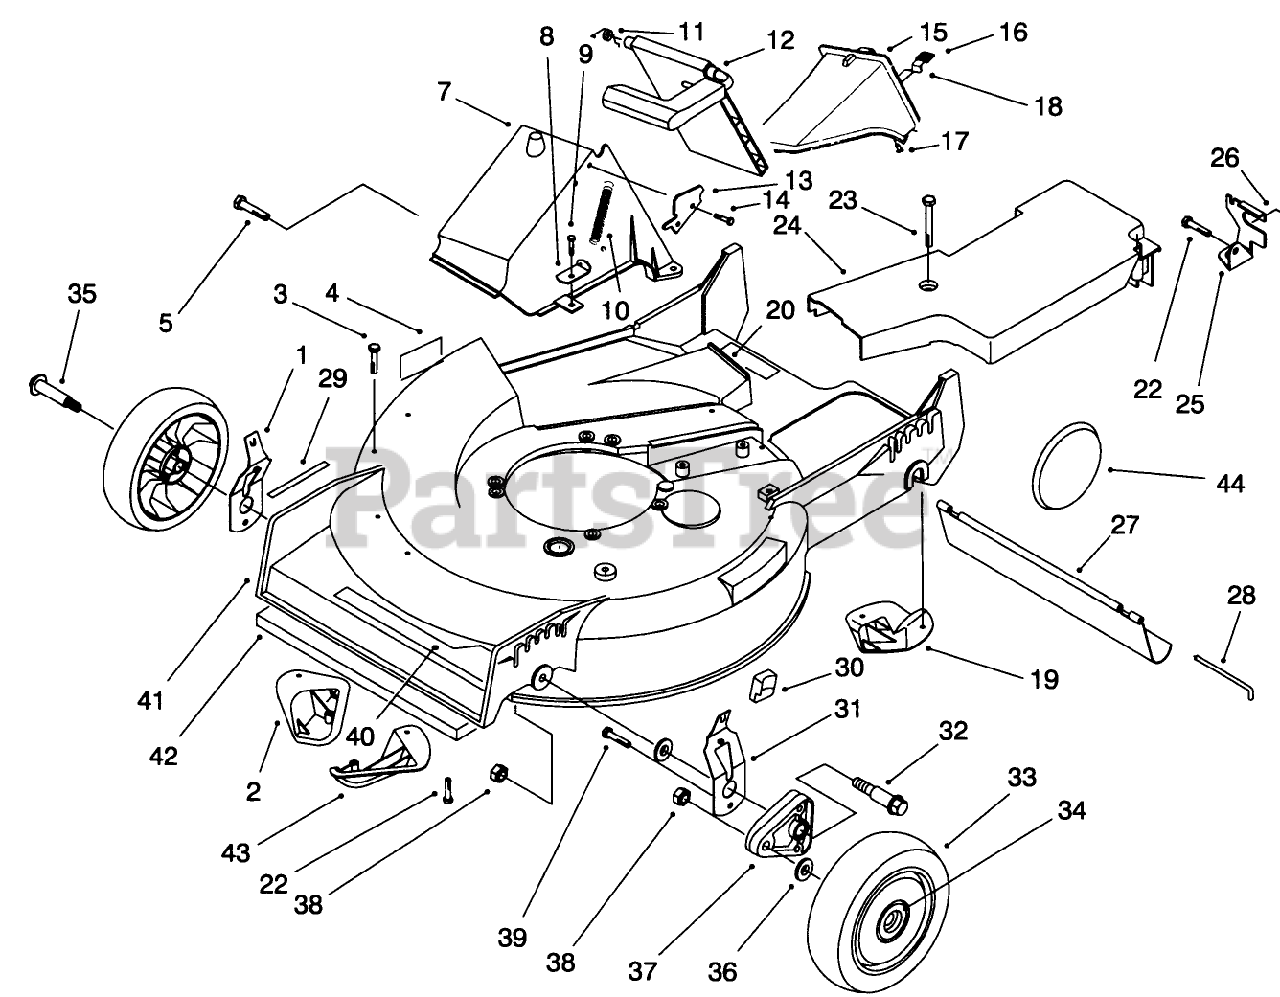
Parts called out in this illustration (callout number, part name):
1	RH SPRING ARM ASSEMBLY
2	KICKER-RH
3	SCREW-PPH
5	SCREW AND WASHER ASM
7	TUNNEL-DISCHARGE
8	BRACKET-SPRING
9	SCREW-HWH
10	SPRING-DOOR
11	RETAINER-DOOR
13	DOOR LATCH PLATE
14	SCREW-PLASTITE
15	DISCHARGE PLUG ASM
16	GRIP-LATCH
17	RIVET-HEAD, FLAT
18	LATCH-PLUG, DISCHARGE
19	KICKER-REAR
22	SCREW-HWHTF
23	SCREW-HWH
26	RETAINER-CABLE
28	ROD-SHIELD
30	KNOB-ARM
31	LH SPRING ARM ASSEMBLY
32	BOLT-SHOULDER
34	BUSHING
36	WASHER
37	ARM-PIVOT, FRONT
38	NUT-LOCK
39	SCREW-HWH
41	SP RECYCLER II DECK ASM
43	KICKER-FRONT
